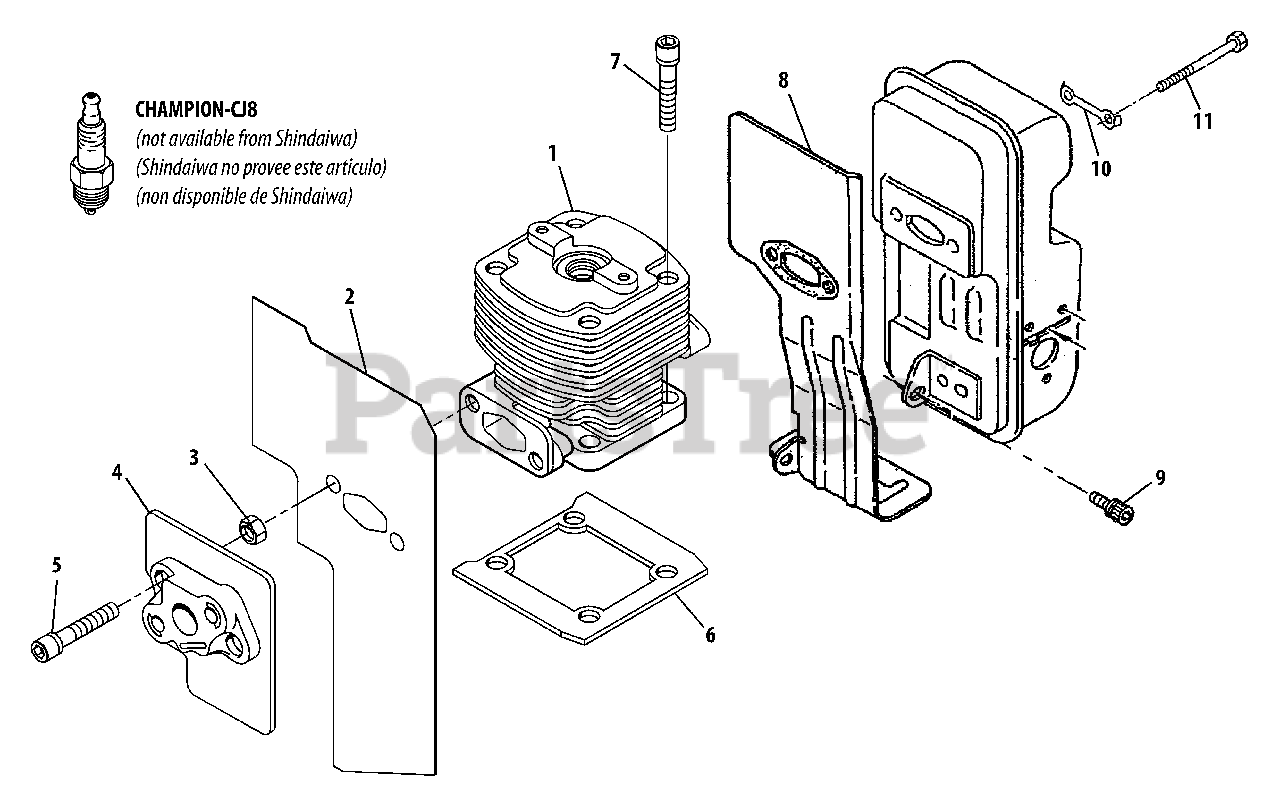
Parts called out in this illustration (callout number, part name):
1	CYLINDER
2	GASKET
3	NUT
4	INSULATOR
5	SCREW - 5X25
6	GASKET, CYLINDER
7	SCREW - 5X25
8	SHIELD, EXHAUST
9	SCREW - 5X12
10	PLATE, LOCK
11	BOLT
